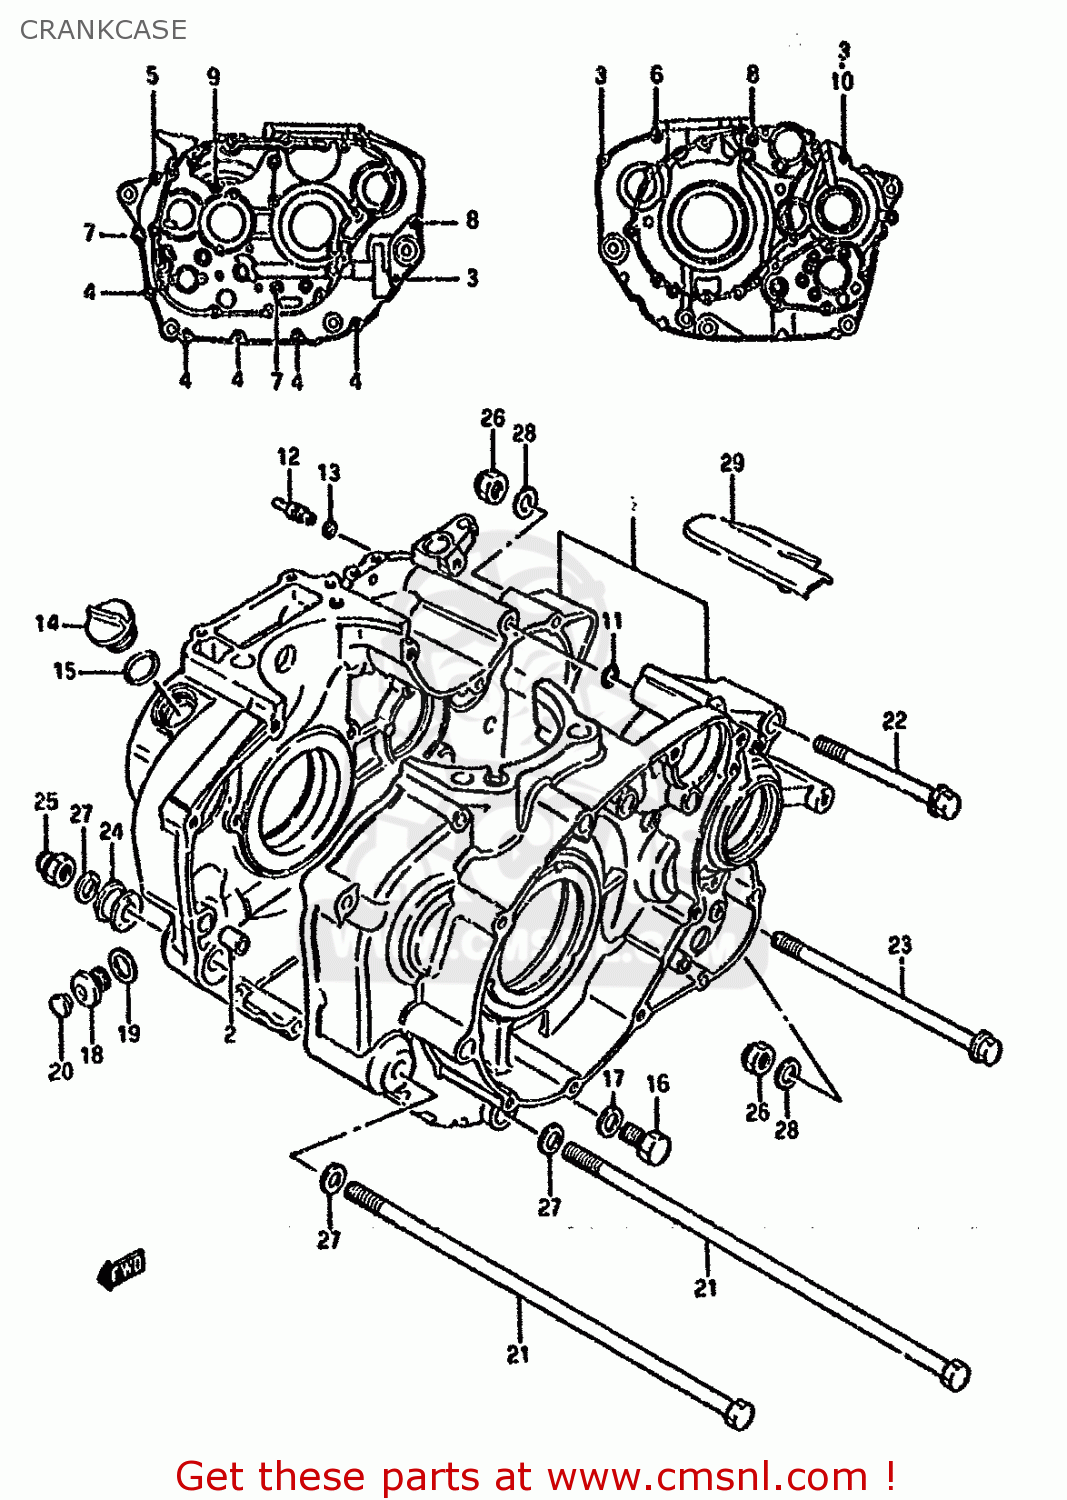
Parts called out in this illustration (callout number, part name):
1	CRANKCASE SET
2	PIN (11X20)(SUS)
3	BOLT
4	BOLT
5	BOLT
6	BOLT
7	BOLT
8	BOLT
9	BOLT
10	GASKET(5.8X13X1.2) (NAS)
11	O RING(D:2.4,ID:9.6)
12	JET,OIL GALLERY(18)
13	O RING(D:1.2,ID:4)
14	PLUG(20X10)
15	O RING(D:3.1,ID:16.8)
16	BOLT
17	GASKET(12.1X16.2X3.7) (NAS)
18	PLUG,14X12
19	GASKET(13.8X18.8X4.8) (NAS)
20	CAP(OD:12)
21	BOLT(10X323)
22	BOLT(10X105)
23	BOLT(10X180)
24	SPACER,ENGINE MOUNT(L20)
25	NUT
26	NUT
27	WASHER
28	WASHER
29	COVER,CRANKCASE START
